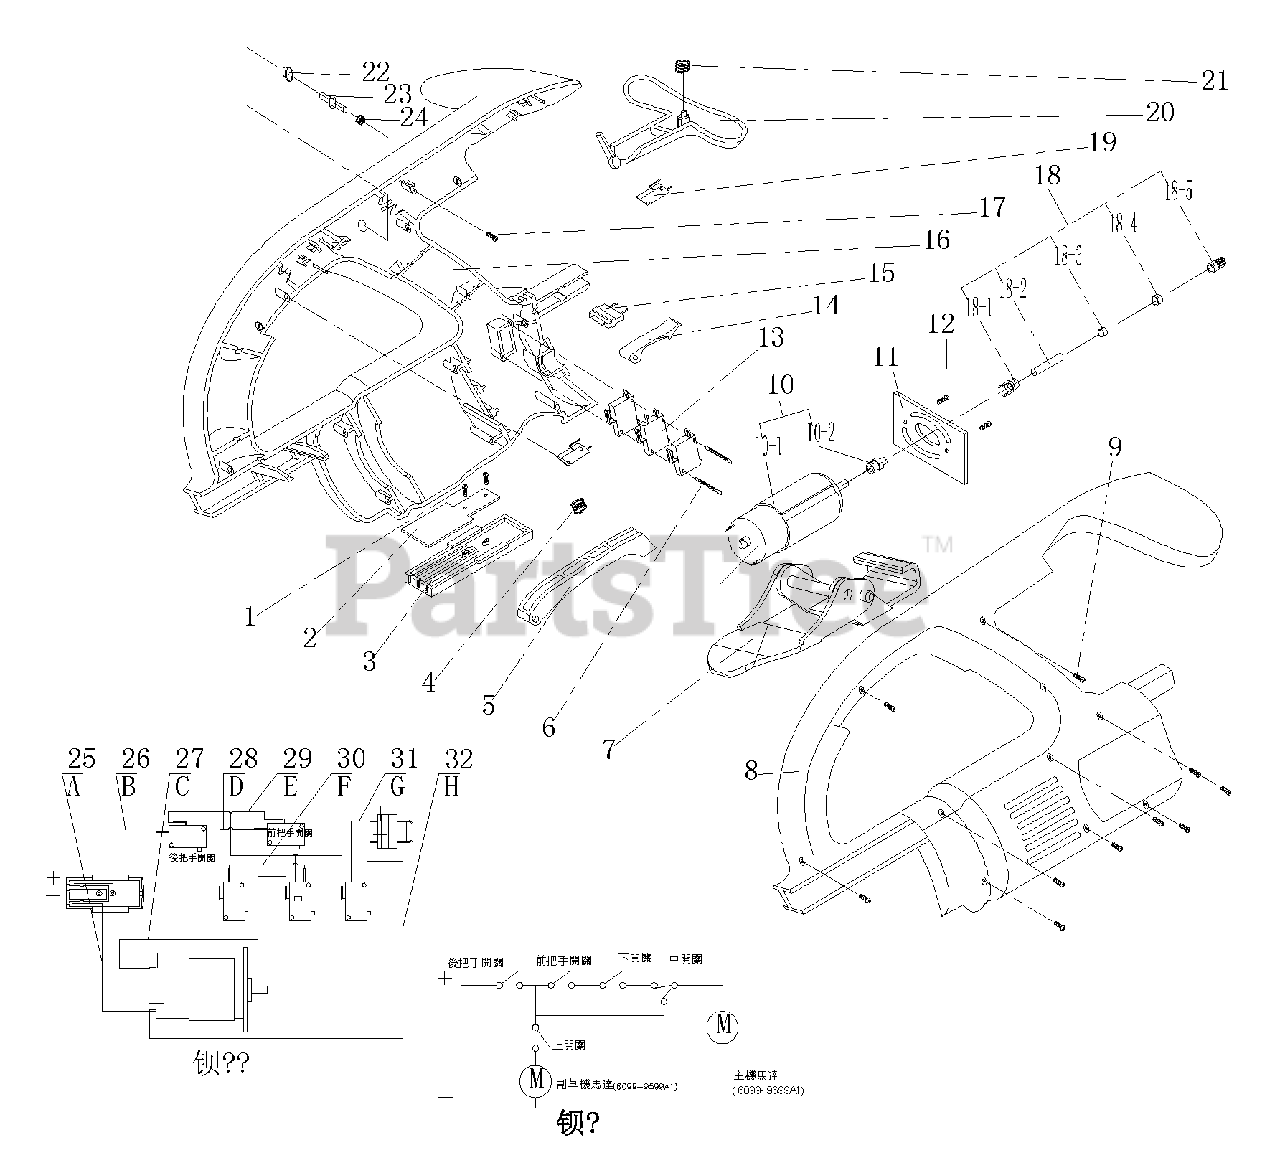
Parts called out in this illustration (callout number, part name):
2	PRESSURE PLATE
3	SOCKET, MAIN BODY
5	BUTTON, AFTER
8	HOUSING (L)
10	MOTOR ASS'Y
11	MOTOR PLATE
15	TERMINAL HOLDER
16	HOUSING (R)
18	SHAFT ASS'Y
20	BUTTON, FRONT
22	SPRING CAP
